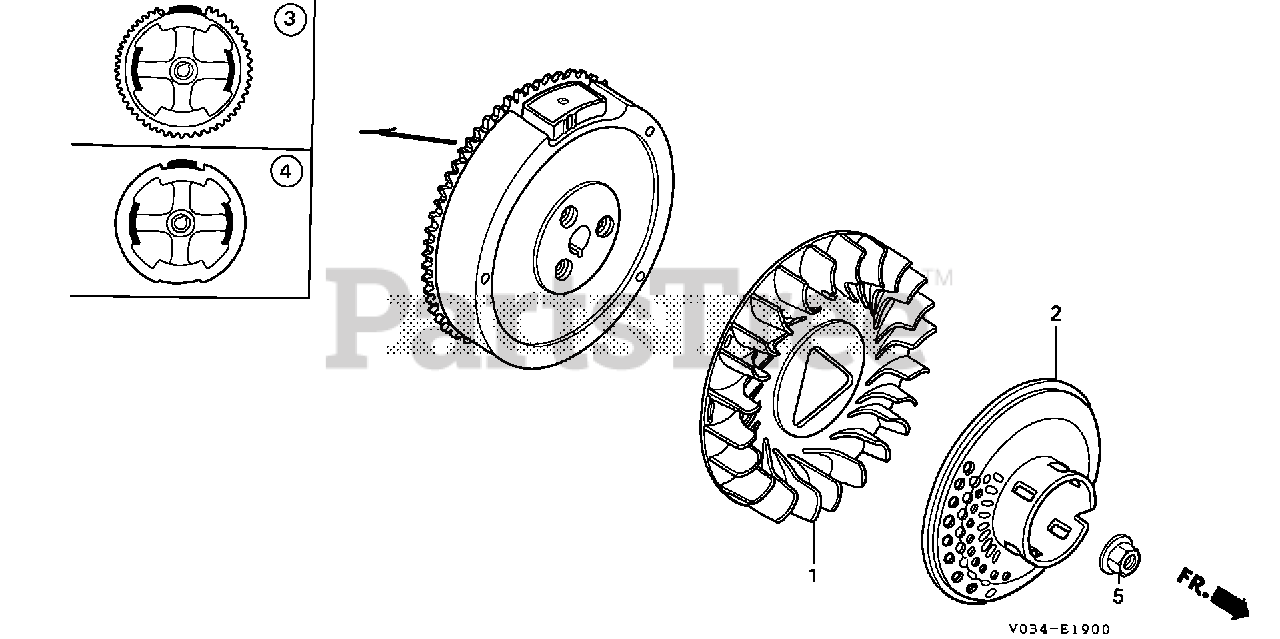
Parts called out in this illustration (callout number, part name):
1	FAN, COOLING
2	PULLEY, STARTER
4	FLYWHEEL (LAMP)
5	NUT, SPECIAL (16MM)
